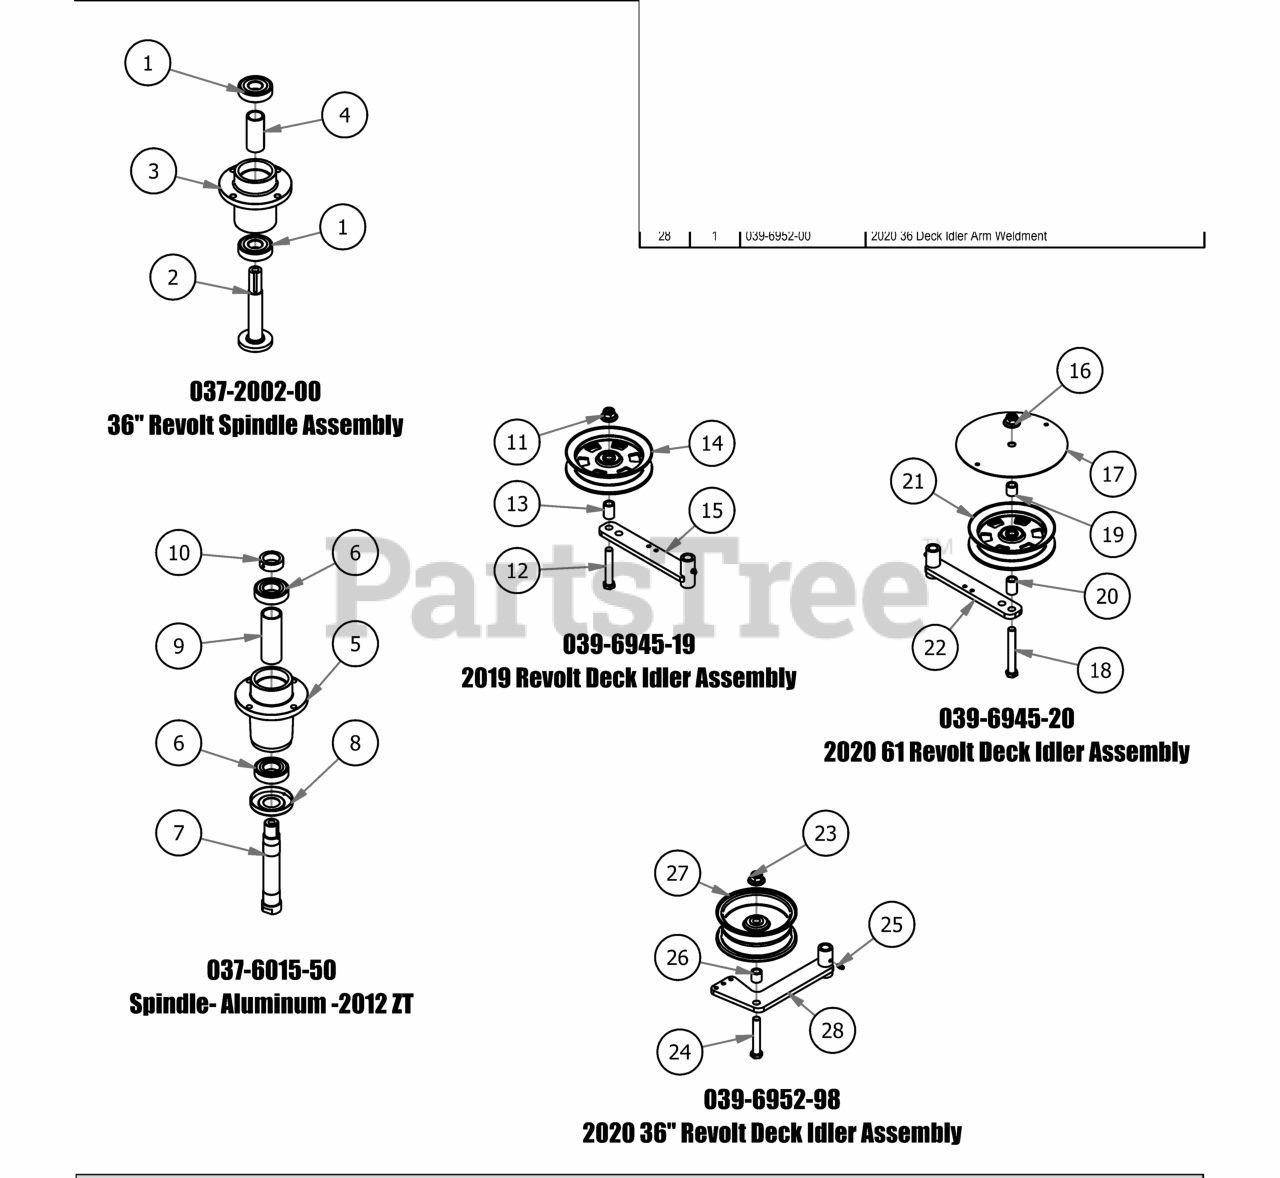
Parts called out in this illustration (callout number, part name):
1	Spindle Bearing
2	36'' Revolt Spindle
3	Spindle Housing
4	Spindle Spacer-Component
5	Aluminum Spindle Housing -2010
6	Spindle Bearing, 2004 and up
7	Short Spindle Shaft w/Locking
8	Dust Cover
9	Tube Spacer for Spindle Shaft
10	Collar Spacer - Top of Spindle
11	1/2-13 NYLON INSERT FLANGE LOCKNUT ZINC
12	1/2-13 x GR 5 Hex Bolt Zinc
14	5" Idler Pully
15	Deck Idler
16	1/2-13 NYLON INSERT FLANGE LOCKNUT ZINC
17	61" Revolt Idler Pulley Cover
18	1/2-13 x 3.75 GR 5 Hex Bolt Zinc
19	Spacer 3/4 OD x 1/2 ID x 3\4 Length
21	5" Idler Pully
22	Deck Idler
23	1/2-13 NYLON INSERT FLANGE LOCKNUT ZINC
24	1/2-13 x GR 5 Hex Bolt Zinc
25	1/4-28 Grease Fitting
26	Spacer 3/4 OD x 1/2 ID x 3\4 Length
27	5 3/4" Deck Idler Pulley
28	2020 36 Deck Idler Arm Weldment
